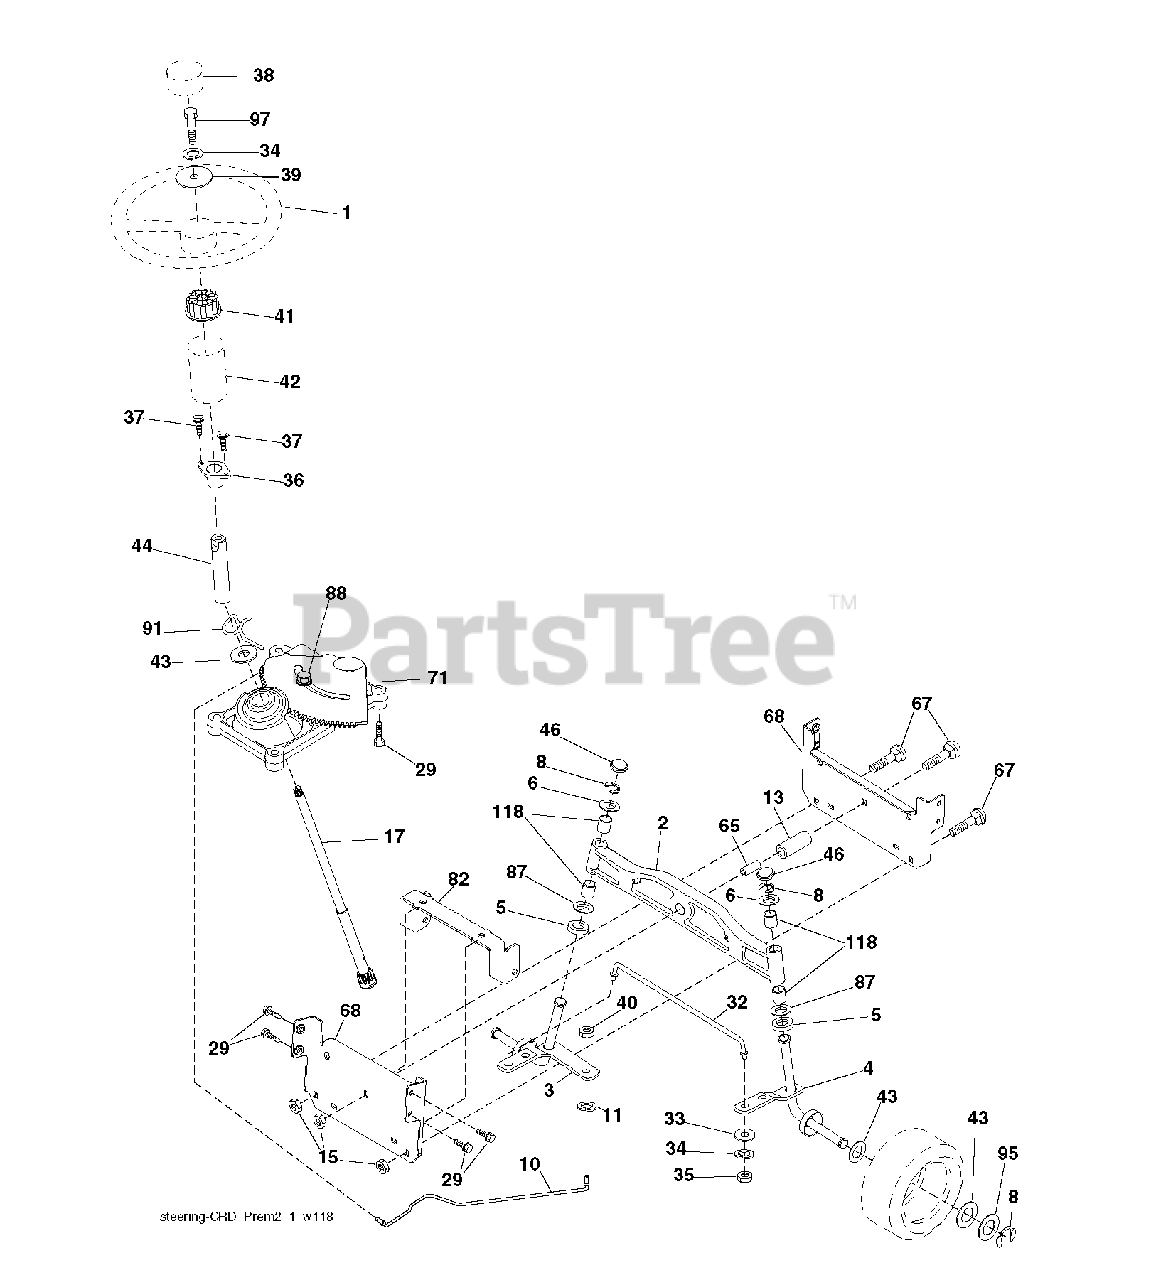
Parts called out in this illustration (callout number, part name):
1	WHEEL.STEERING.STDSRR.BLK/OV
2	AXLE.ASM.LT.CAST.LGHTWGHT
3	SPINDLE.ASM.LH.15"TIRES
4	SPINDLE.ASM.RH.15"TIRES
8	RING CLIP
10	DRAGLINK.15".TIRES.2001
11	WASHER, LOCK 3/8
13	TUBE, PIVOT AXLE
15	NUT LOCK FLG 3/8-16 UNC
17	SHAFT STEERING SPLINE
29	SCREW, 3/8-16X3/4
32	ROD.ASM.TIE.BALL.JOINT.NOVAN
33	WASHER M
34	LOCKWASHER
35	NUT, CROWNLOCK
36	BUSHING, STEERING
38	CAP.WHL.STRNG.STDSRRD.SRS.BLK
39	WASHER.11/32
40	NUT CROWNLOCK 3/8-24
41	ADAPTER, WHEEL STNG..
42	BOOT.STEERING.SHAFT.BLACK
44	SHAFT.EXTEN.STRG.SPLINE
46	CAP.SPINDLE
65	SPACER.BRACE.AXLE
67	BOLT CARRIAGE
68	BRACE.AXLE.15"TIRES
71	STEERING ASM
82	BRACKET.SUSP.CHASSIS.FRONT.15
87	WASHER, FLAT .781 X 1 1/2"
88	BOLT, SHOULDER 7/16-20
91	CLIP.STEERING
95	WASHER.HARDENED
97	BOLT 5/16-18 X 4 W/PATCH
118	BUSHING, AXLE CAST
